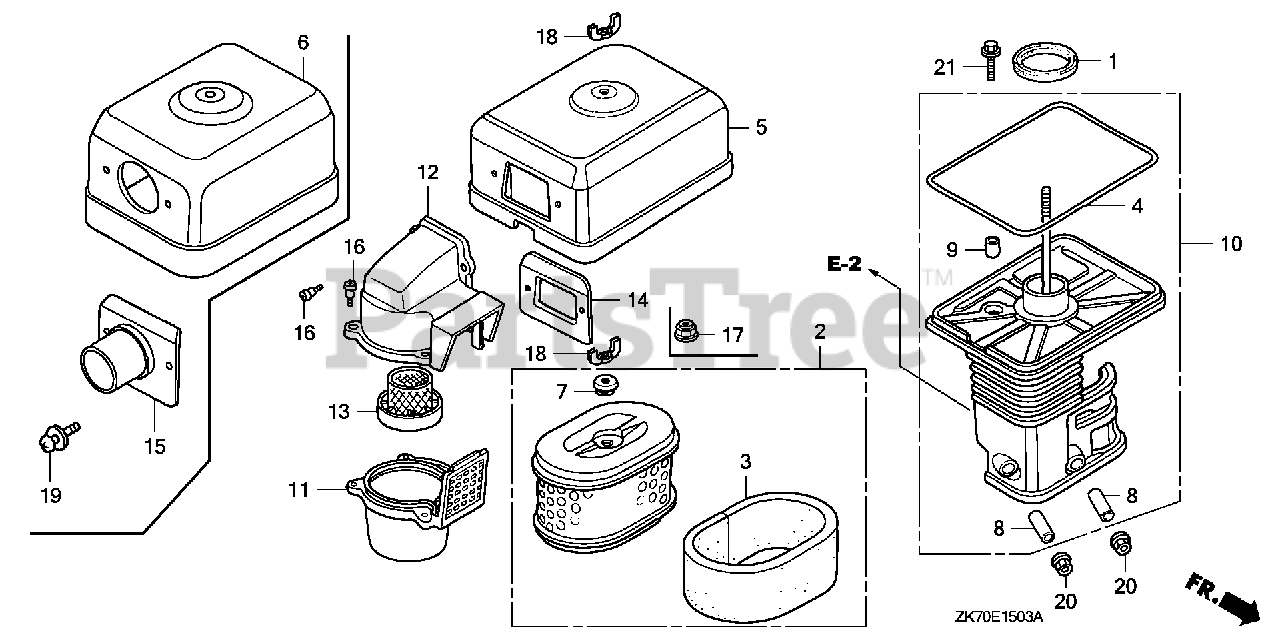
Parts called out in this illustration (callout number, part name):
1	GASKET, ELBOW
2	ELEMENT, AIR CLEANER (DUAL)
3	FILTER (OUTER)
4	GASKET, AIR CLEANER COVER
5	COVER, AIR CLEANER (CYCLONE)
7	GROMMET, AIR CLEANER
8	COLLAR, AIR CLEANER
9	COLLAR B, AIR CLEANER
10	ELBOW, AIR CLEANER
11	CASE, PRE AIR CLEANER
12	CAP, PRE AIR CLEANER
13	GUIDE, PRE AIR CLEANER
14	PLATE, PRE AIR CLEANER
16	BOLT, SPLASH GUARD
18	NUT, TOOL BOX SETTING
20	NUT, FLANGE (6MM)
21	BOLT, FLANGE (6X20)
